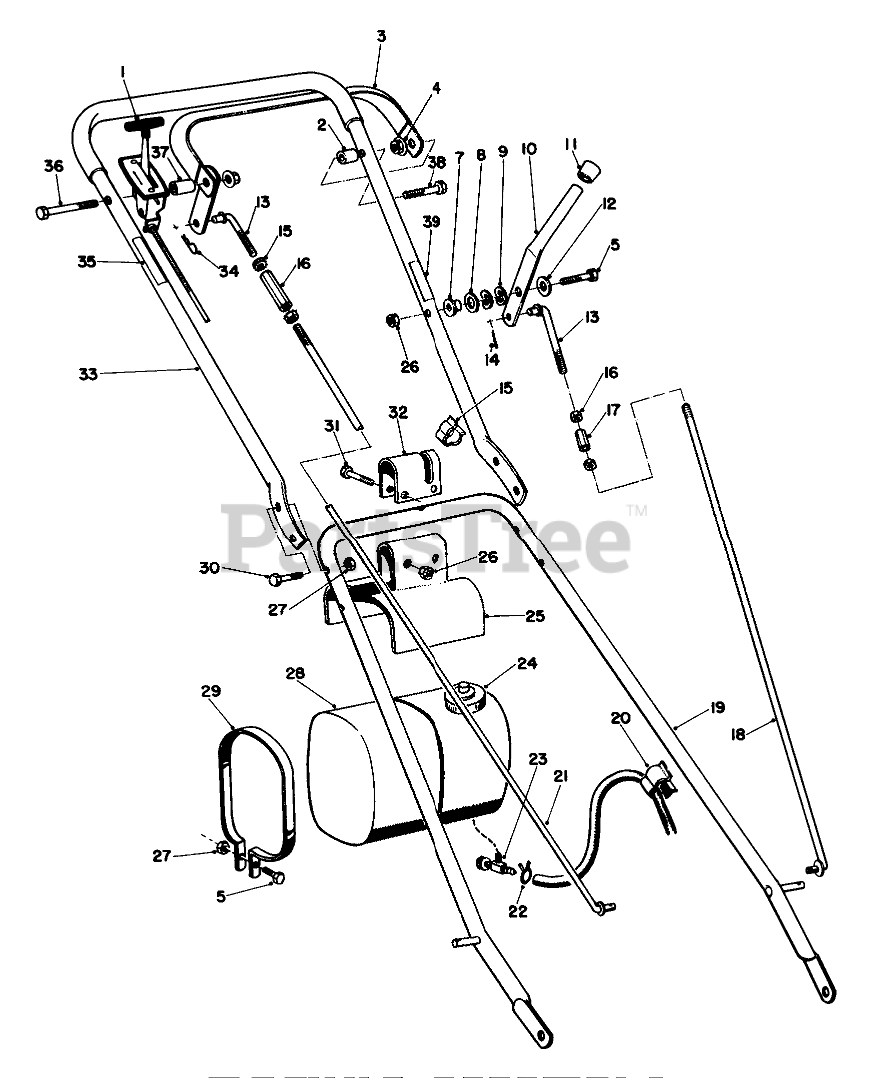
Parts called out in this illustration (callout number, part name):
1	Control, Throttle
2	Spacer
3	Control Bail
4	NUT-LOCK, HHF
5	SCREW-HH
7	PIVOT
8	WASHER-FLAT
9	WASHER-SPRING
10	CUTTER HANDLE R
11	Button Plug
12	WASHER-FLAT
13	LINK CONTROL ROD
14	PIN-COTTER
15	Clamp
16	NUT-KEPS
17	CONTROL ROD SLEEVE
18	CUTTER CONTROL ROD
19	LOWER HANDLE WA
20	CLAMP
21	CONTROL ROD
22	Clamp
23	.125 ID SHUTOFF VALVE
25	FUEL TANK BRACKET
26	Nut
27	NUT-LOCK
28	Tank
29	TANK STRAP
30	SCREW-HH
31	SCREW-HH
32	Clamp
33	Upper Handle
34	PIN-COTTER
35	Decal-Throttle
36	SCREW-HH
37	SLEEVE-PIVOT ROLLED
38	SCREW-HH
39	BLADE CONTROL DECAL
